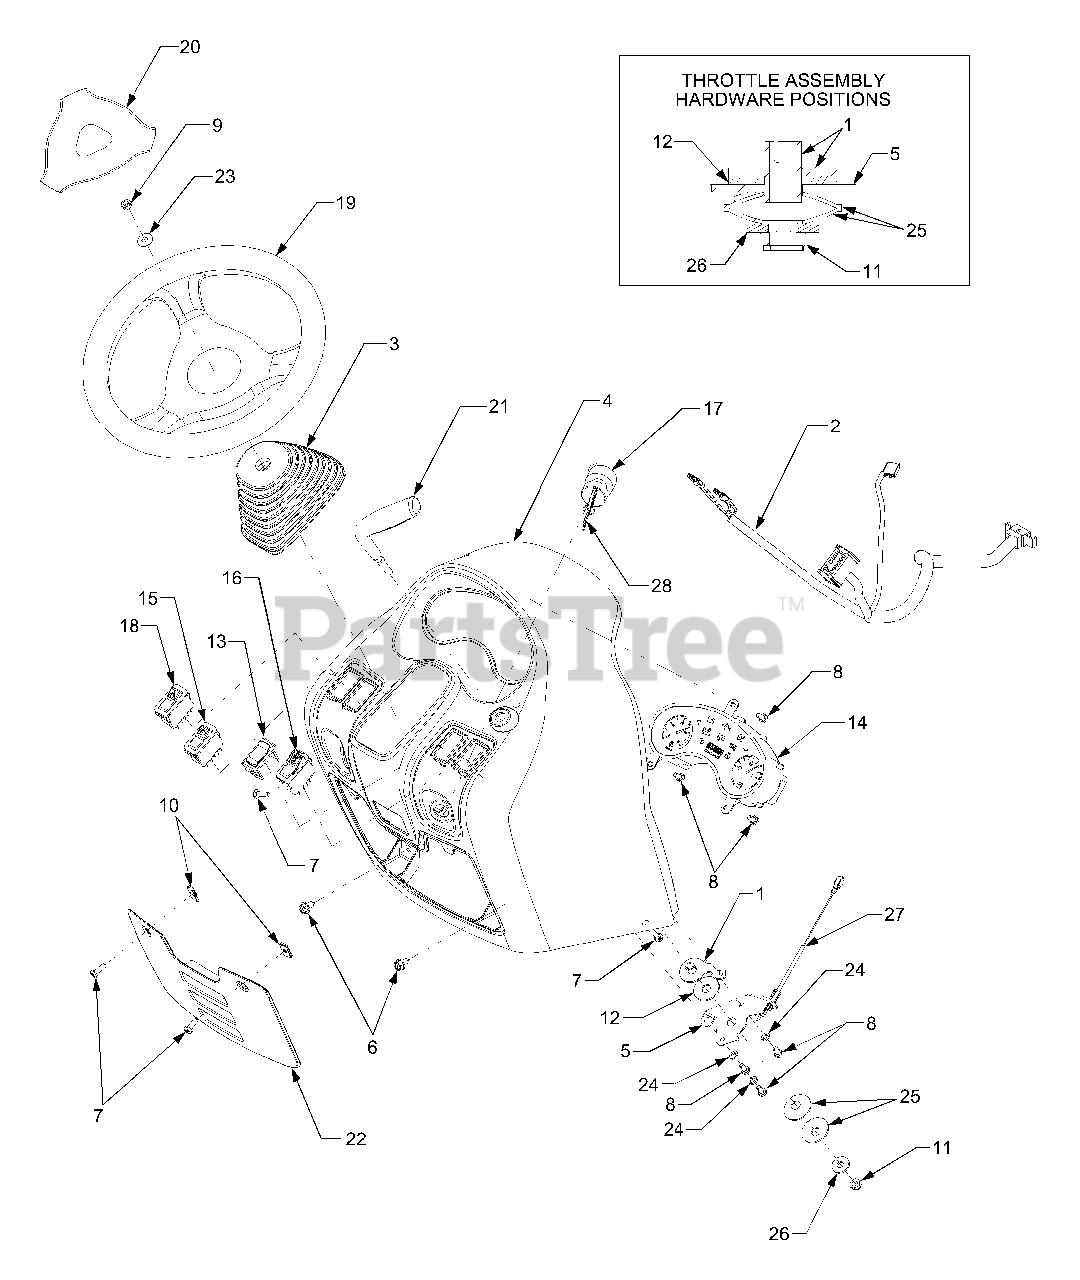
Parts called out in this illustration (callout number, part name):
3	Boot, Steering Shaft
4	Dash
5	Plate, Throttle Mtg.
6	Screw, Hex Wash. Hd. Tapp 5/16-18 x .625
7	Screw, Pan Hd., 1/4-20 x .75
8	Screw, Hex Cap, 1/4-20 x .5 GR5
9	Nut, Hex Lock, 5/16-24
10	Nut, Speed, 1/4-20
11	Nut, Hex Insert Jam Lock, 3/8-24
12	Washer, Friction, .515 x 1.5 x .12
14	Panel, Instrument
15	Switch, Headlight
16	Switch, PTO
17	Switch, Ignition
18	Switch, Hazard
19	Steering Wheel, Soft Grip
20	Cover, Steering Wheel
21	Handle, Throttle
22	Panel, Dash Insert
23	Washer, Belleville, .34 x .872 x .06
24	Washer, Lock, 1/4
25	Washer, Belleville, .531 x 1.62 x .045
26	Washer, Flat, .406 x 1.0 x .105
27	Cable, Throttle
28	Key Set, Ingition
